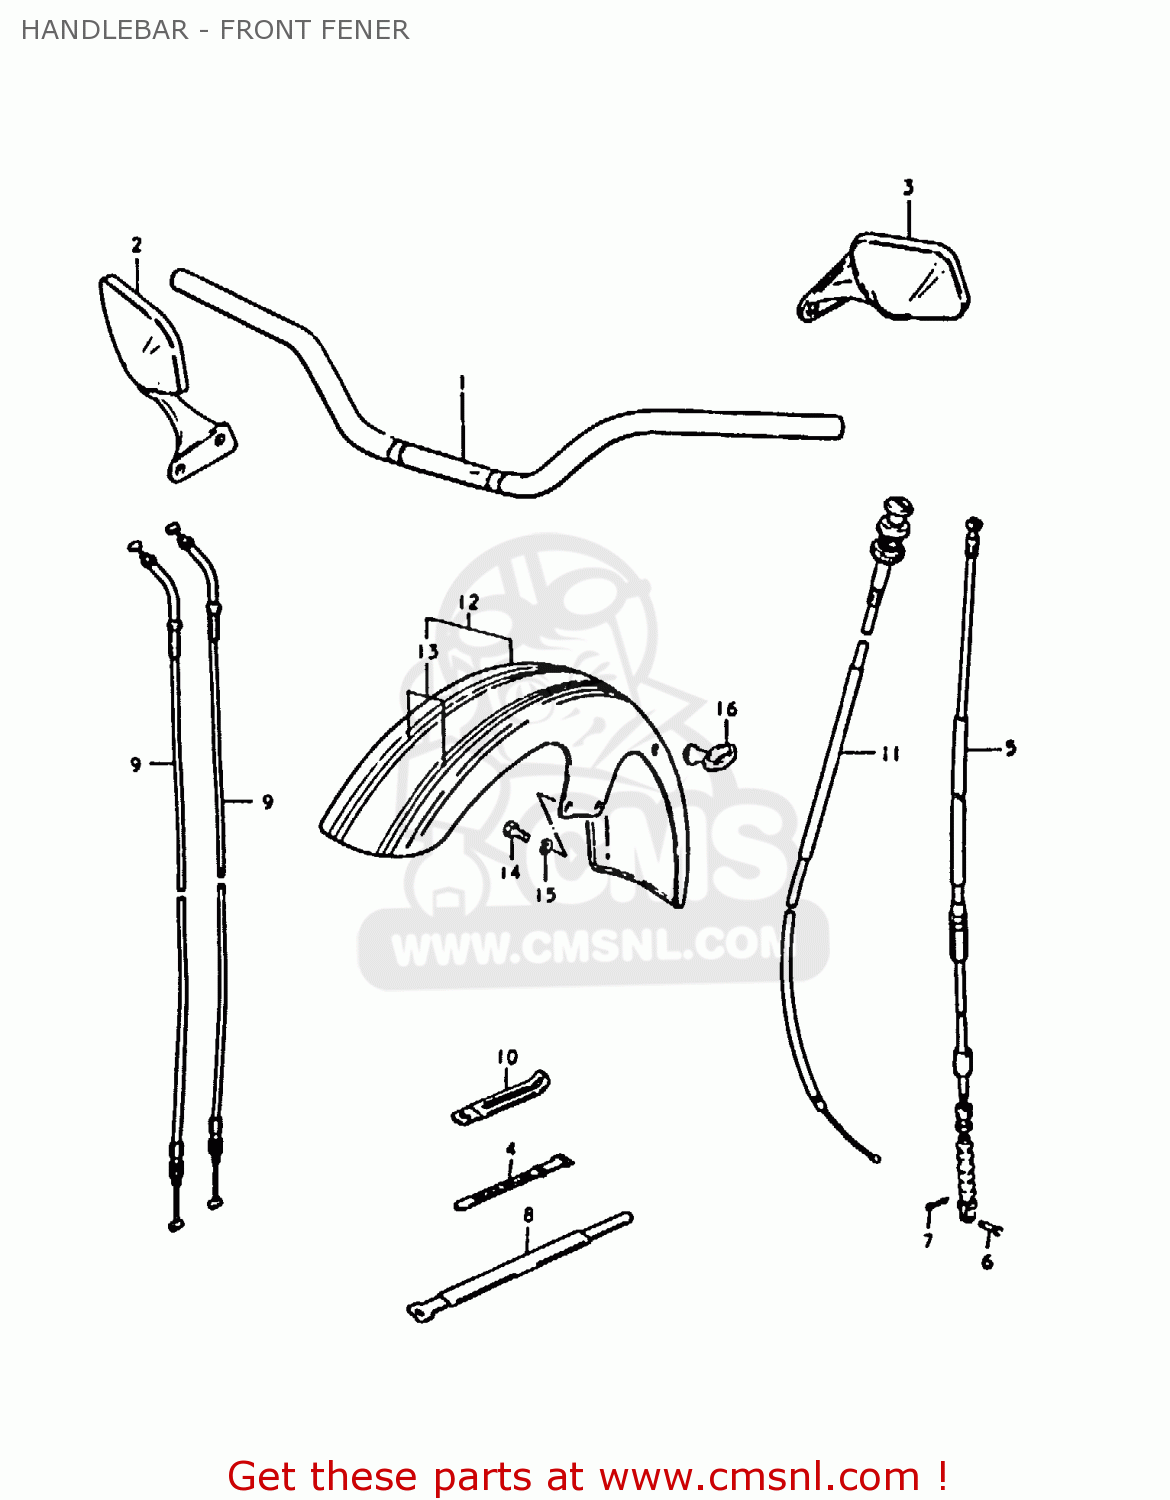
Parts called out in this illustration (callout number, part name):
1	HANDLEBAR
2	MIRROR ASSEMBLY,RIGHT
3	MIRROR ASSEMBLY,LEFT
4	CLAMP(L:120)
5	CABLE,CLUTCH
6	PIN(L:15)
7	PIN
8	CLAMP
9	CABLE ASSY,THROTTLE
10	CLAMP
11	CABLE ASSY,STARTER
12	FENDER,FRONT
13	TAPE SET,FRONT FENDER STRIPE
14	BOLT
15	LOCK WASHER
16	GUIDE,CABLE
